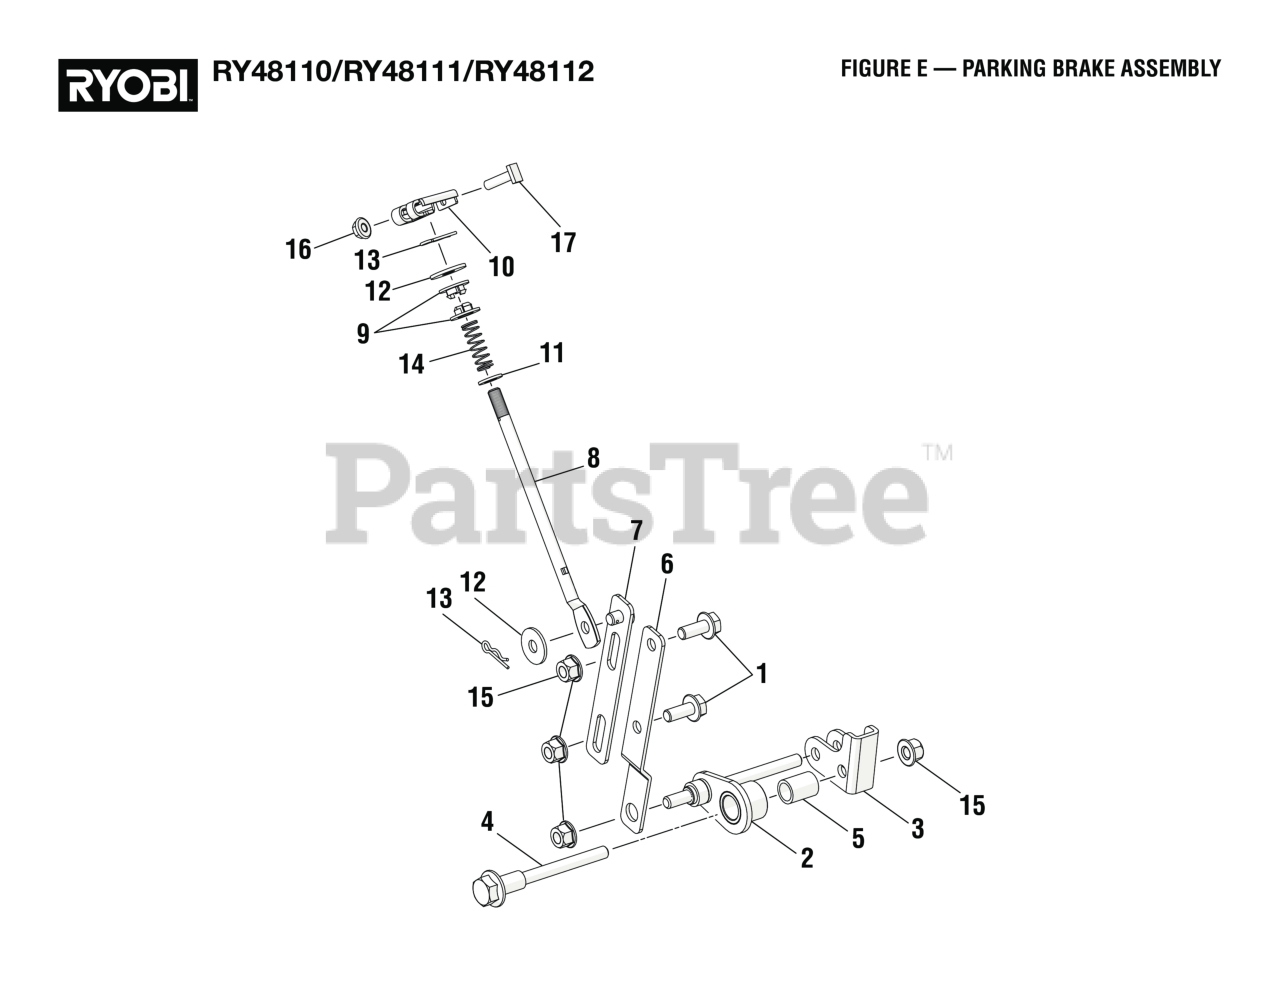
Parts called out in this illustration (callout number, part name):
1	Flange Bolt (M8 x 20 mm, Hex Hd.)
2	Pivot Bracket
4	Center Step Bolt
5	Nylon Sleeve
6	Lower Connecting Plate
7	Upper Connecting Plate Assembly
8	Upper Rod
9	Spring Capture Bushing, Nylon
10	Lever Bracket
11	Washer (OD16 x ID8.4 x 1.6t)
12	Washer (OD 24 x ID8.4 x 2t)
13	Cotter Pin (8 mm)
14	Compression Spring
15	Flange Nut (M8) (For Drive Motor Controller V)
16	Flange Lock Nut (M6 x 1.00)
17	Screw (M6 x 22 mm, Rectangle Hd.)
